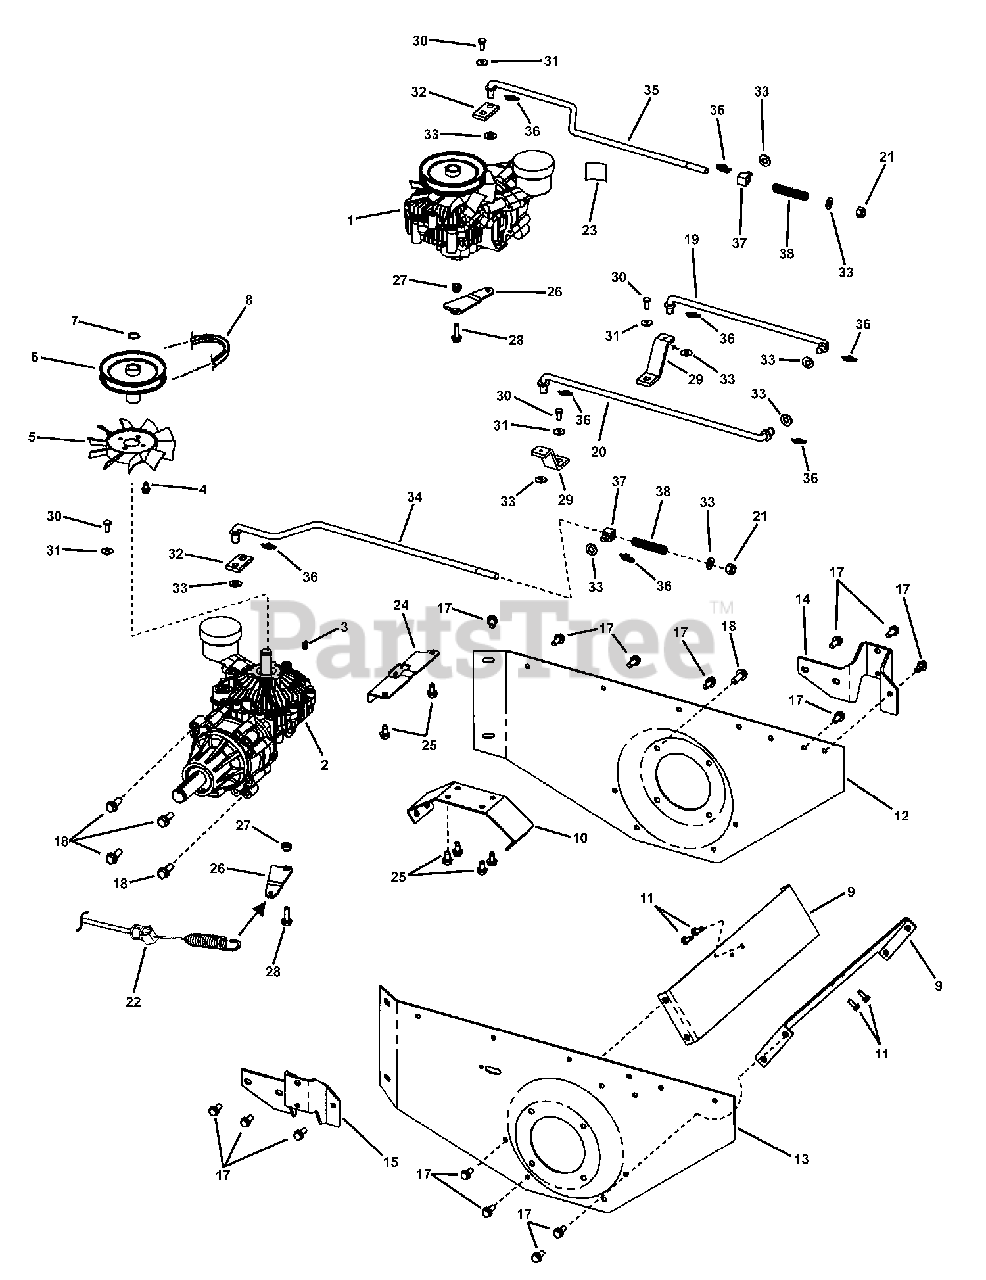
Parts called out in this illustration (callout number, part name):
1	TRANSAXLE, Hydro
2	TRANSAXLE, Hydro w/o Manifold R.H.
3	KEY, #605 Woodruff
4	SCREW, 1/4-20 x 1/2" Hex Washer Self-Tap
5	FAN, 6" O.D., 10 Blade
6	PULLEY, Hydro Input
7	RING, RR3100-66 External Retaining
8	V-BELT, HA Sect. 42.5" effective length
9	BRACKET, Support, Fender
10	BRACKET, Support, Hydro
11	SCREW, 1/4-20 x 5/8" Hex Washer Self-Tap
12	FENDER, Rear Frame, Left Hand
13	FENDER, Rear Frame, Right Hand
14	BRACKET, Deck Support, Left Rear
15	BRACKET, Deck Support, Right Rear
17	SCREW, 5/16-18 x 3/4" Hex Washer Self-Tap
18	SCREW, 3/8-16 x 1" Hex Washer Self-tap
19	TRANSMISSION ROD, RH, Twin Stick
20	TRANSMISSION ROD, LH, Twin Stick
21	NUT, 3/8-16 Hex Nyloc
22	CABLE, Hydro Release Valve
23	DECAL, Hydro Reservoir
24	BRACKET, Cable, Hydro Release Valve
25	SCREW, 5/16-18 x 5/8" Hex Washer Self-Tap
26	BRACKET, Actuator, Hydro Release Valve
27	BUSHING, Differential Link, Powdered Metal
28	SCREW, 5/16-18 x 1" Hex Washer Self-Tap, GR 5
29	ARM, Direction Control- Hydro Transaxle
30	BOLT, 1/4-28 x 5/8" w/Nyloc Patch, GR 8
31	WASHER, 1/4" Belleville
32	ARM, Brake
33	WASHER, 3/8" SAE Flat
34	BRAKE ROD, RH (3/8-16 thread)
35	BRAKE ROD, L. H. (3/8-16 thread)
36	COTTER-PIN, 1/16" x 1.42" Self-Locking
37	SWIVEL, Brake Link- PM
38	SPRING, Brake Compression
